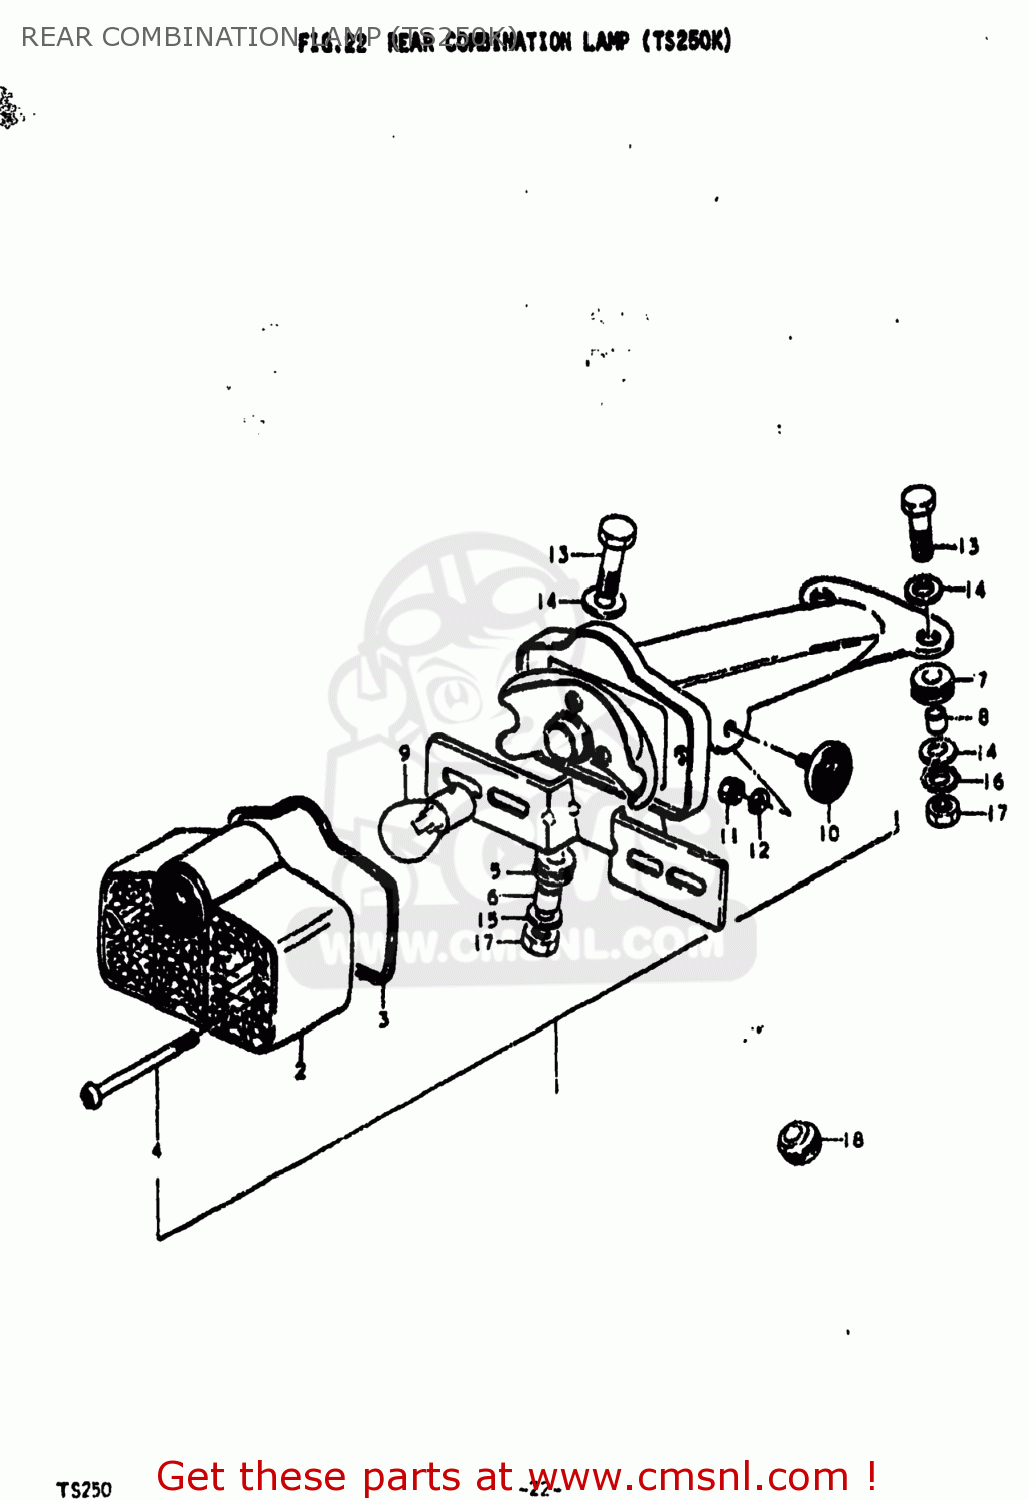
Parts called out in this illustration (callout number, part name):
1	LAMP ASSEMBLY,REAR COMBINATION
2	LENS,REAR COMBINATION LAMP
3	GASKET (NAS)
4	SCREW
5	CUSHION
6	SPACER,REAR COMBINATION LAMP
7	CUSHION
8	SPACER,REAR COMBINATION LAMP
9	BULB(6V32/3CP,STANLEY)
10	REFLECTOR,REFLEX
11	NUT
12	LOCK WASHER
13	BOLT
14	WASHER (6.5X20X1.2)
15	LOCK WASHER
16	LOCK WASHER
17	NUT
18	GROMMET
